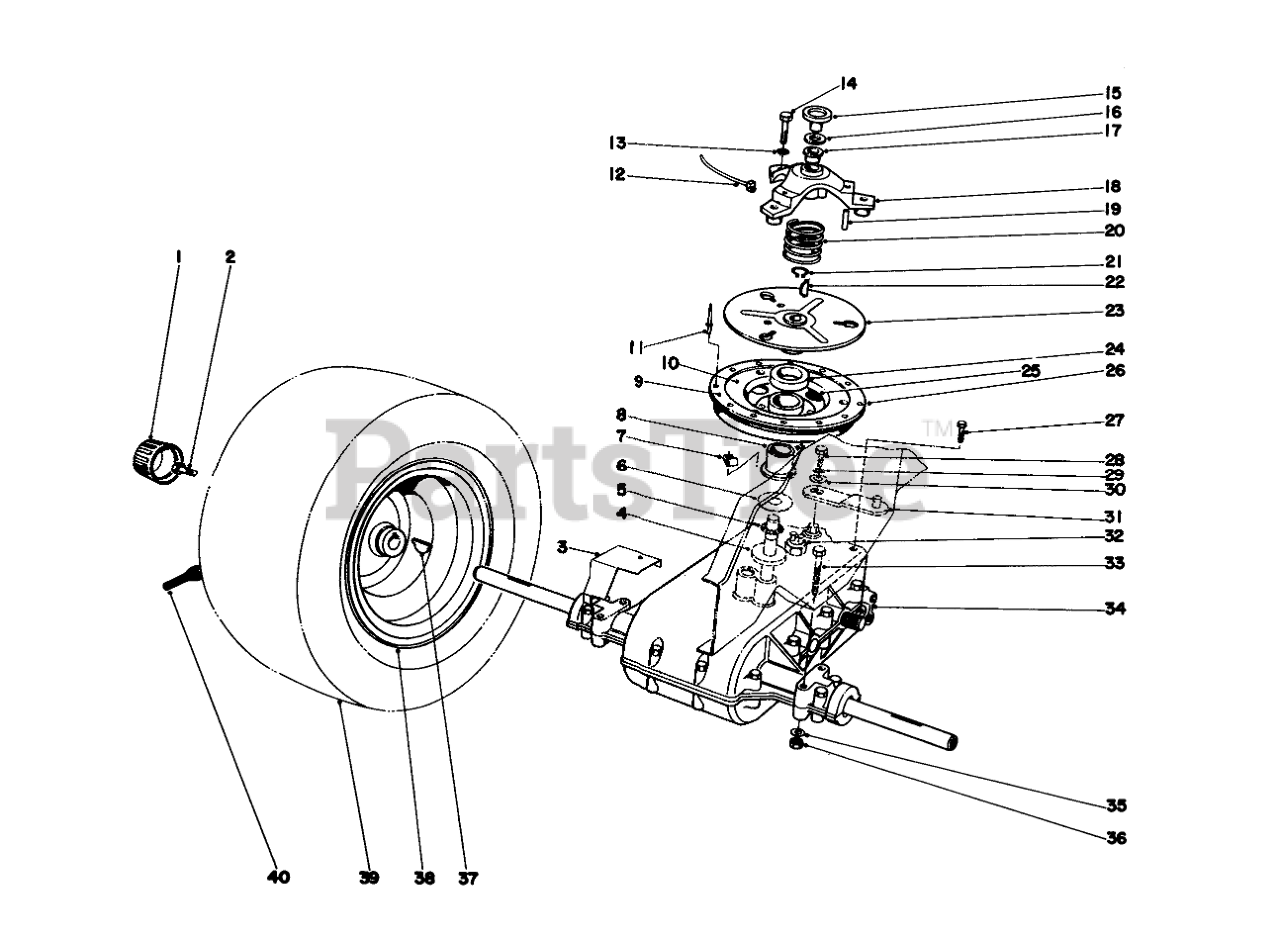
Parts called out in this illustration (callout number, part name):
1	Cap-Hub
2	CAPSCREW 3/8 16 3/4
3	GRASS SHIELD B
4	SPACER
5	NEEDLE BRG
6	THRUST WASHER
7	CLIP-FUEL LINE
8	Bushing
9	CLUTCH PAD
10	Retainer Ring
11	Rivet
12	TIE-MOUNT, PUSH
13	WASHER-LOCK
14	SCREW-HH
15	CLUTCH CAP
16	THRUST RACE
17	BUSHING-FLANGE
18	Clutch Cover (Incl. Ref. #17 & 19)
19	NEEDLE BRG
20	COMPRESSION SPRING
21	RING-SNAP, EXTERNAL
22	KEY-WOODRUFF
23	Clutch Plate
24	WASHER FELT
26	Sheave Assembly (Incl. Ref. #8-11)
27	SCREW-HWHTF
28	SCREW-HH
29	WASHER-LOCK
30	WASHER-FLAT
31	SHIFT LEVER WA B
32	NEUTRAL SWITCH
33	SCREW-HH
34	Transaxle
35	WASHER-PLAIN
36	NUT-LOCK, CONE
38	Rim
39	16 X 7.5-8 REAR TIRE
40	STEM-VALVE
